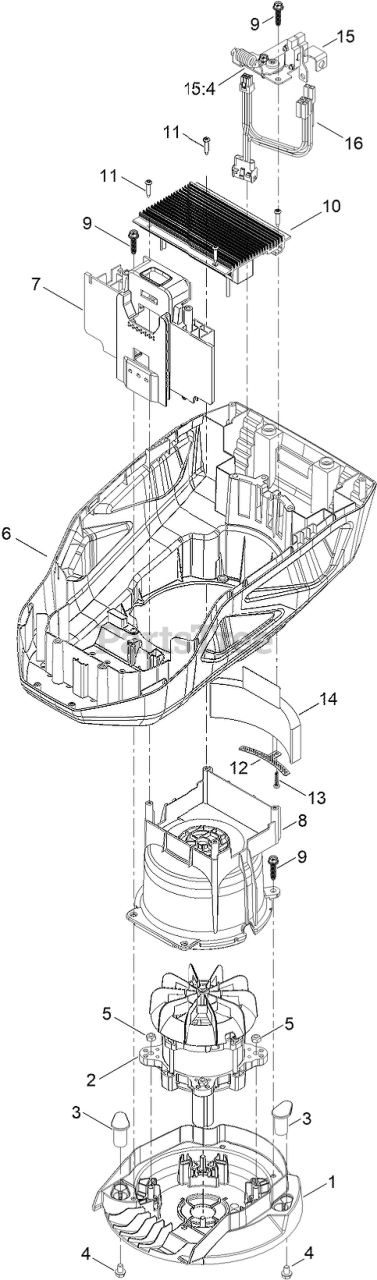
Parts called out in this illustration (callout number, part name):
1	BASE-MOUNT, MOTOR
2	MOTOR-2KW
3	INSERT-MOUNT, Motor
5	NUT-LOCK
6	SHROUD-LOWER
7	MOUNT-BATTERY
8	SHROUD-MOTOR
9	SCREW-FLANGE, PLASTIC
10	CONTROLLER-MOTOR
12	BRACKET-FOAM
13	SCREW-PLASTIC, PPH
15	BAIL SWITCH ASM
15:4	SPRING-EXTENSION
16	HARNESS-WIRE
